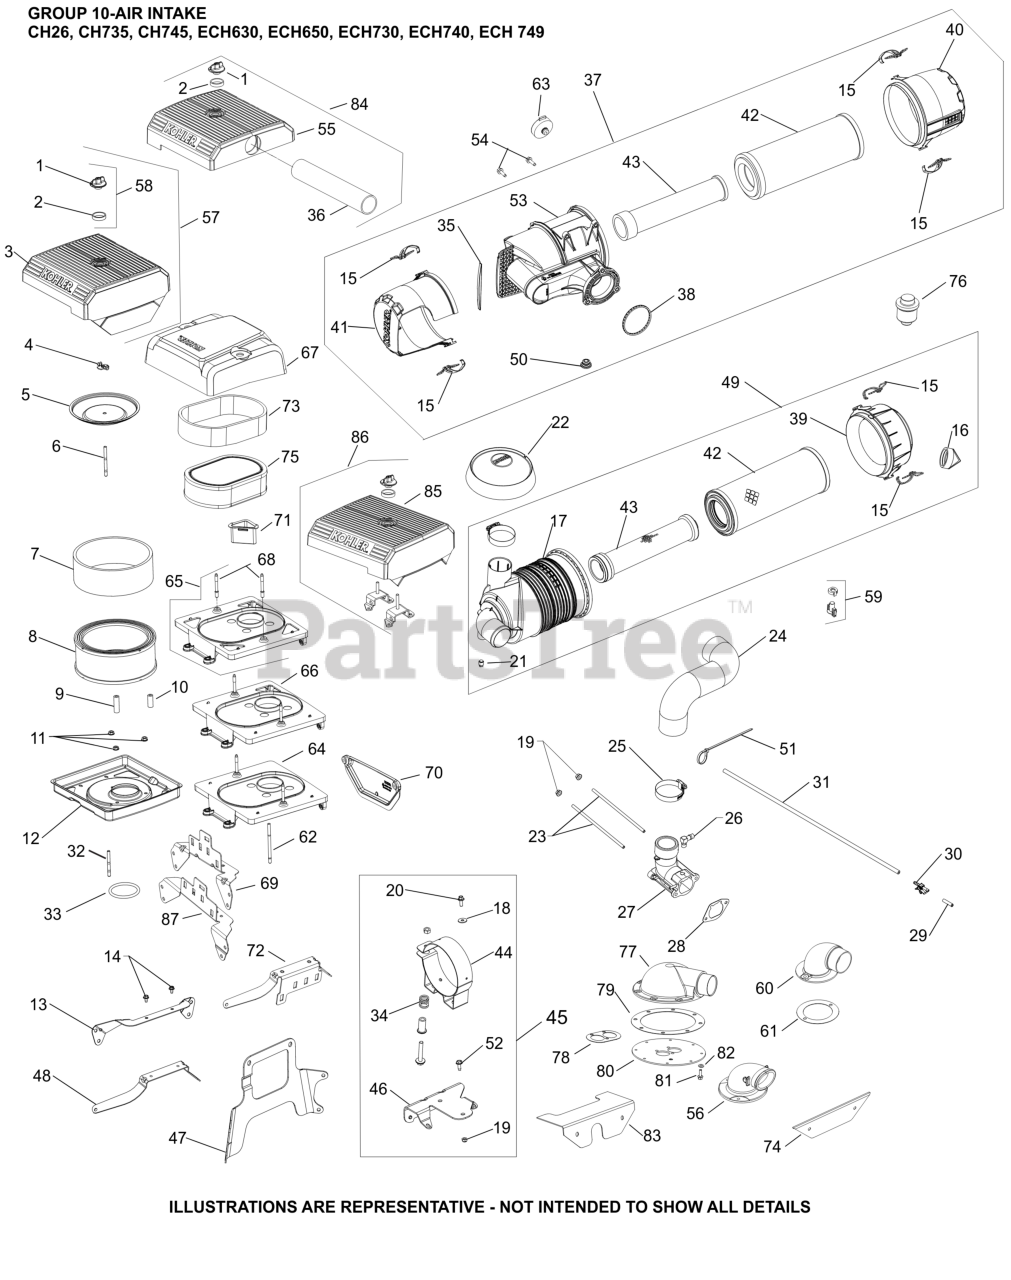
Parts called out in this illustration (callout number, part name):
1	KNOB, COVER
11	NUT, FLG M6X1.0
29	CAP, MASKING
30	CONNECTOR, EVAPORATIVE
38	O-RING (HDAC SEAL-EFI)
58	KIT, KNOB W/SEAL
65	BASE, AIR CLEANER ASSEMBLY (LPAC-ETB)
66	BASE, AIR CLEANER ASSEMBLY (LPAC-ETB)
67	COVER, AIR CLEANER (LPAC - ETB)
68	STUD, 6.3 X 1.69 HI-LO / M6 X 1
71	DUCT, AIR (LPAC - ETB)
73	ELEMENT, PRE-CLEANER
75	ELEMENT, AIR FILTER (ETB)
87	BRACKET, LPAC SUPPORT (ETB)
